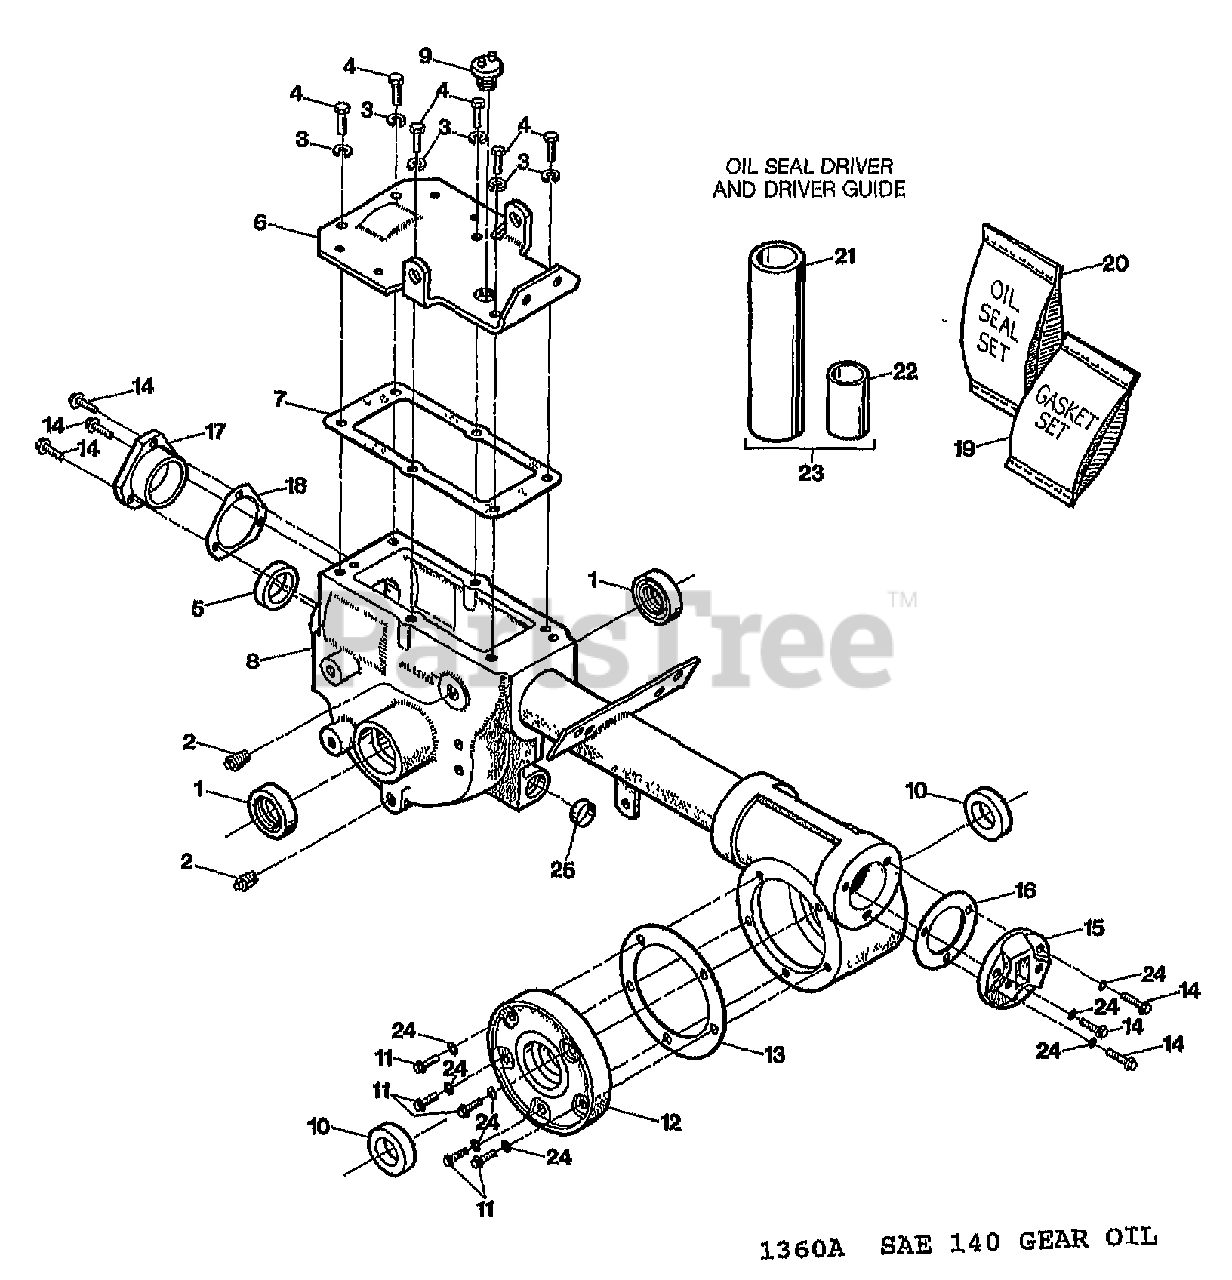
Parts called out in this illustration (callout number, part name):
1	SEAL-OIL WHEELSHAFT (RT & LT SIDES)
2	PLUG-PIPE 1/4 NPT (OIL LVL & GEAR OIL DRAIN)
3	WASHER-LK .312 ZP (TRANS TOP COVER)
4	SCR-HHC 5/16-18X.75 GR 5 ZP (TRANS TOP COVER)
5	SEAL-PINION SHAFT PT/85030/00 (INP PNION SHFT)
6	COVER-TRANS (TOP OF TRANS)
7	GASKET-TRANS COVER (TRANS TOP COVER)
8	HSG-TRANS P5 A UNIT (INCL #9429 REAR BRG RACE)
9	PLUG-OIL FILL 3/4-10 (GEAR OIL FILL)
10	SEAL-TILLER SHAFT (LT & RT SIDES)
11	SCR-HH 1/4-20X.625
12	COVER-LFT W/SCRS&RACE (INCL 5 #9780 BLTS)
13	GASKET-TILLER COVER (FITS ALL COVERS)
14	SCR-HFLK 1/4-20X.875
15	CAP-REAR #1115
16	GASKET-BRG COVER
17	COVER-FRONT BEARING
18	GASKET-FRONT COVER-.010
19	GASKET SET-P4
20	OIL SEAL SET-PONY V
21	DRIVER-PLASTIC
22	SEAL-DRIVER PILOT
23	KIT-DRIVER (INCL. 21,22)
24	WASHER, NYLON (NOT REUSABLE)
25	PLUG-BORE
